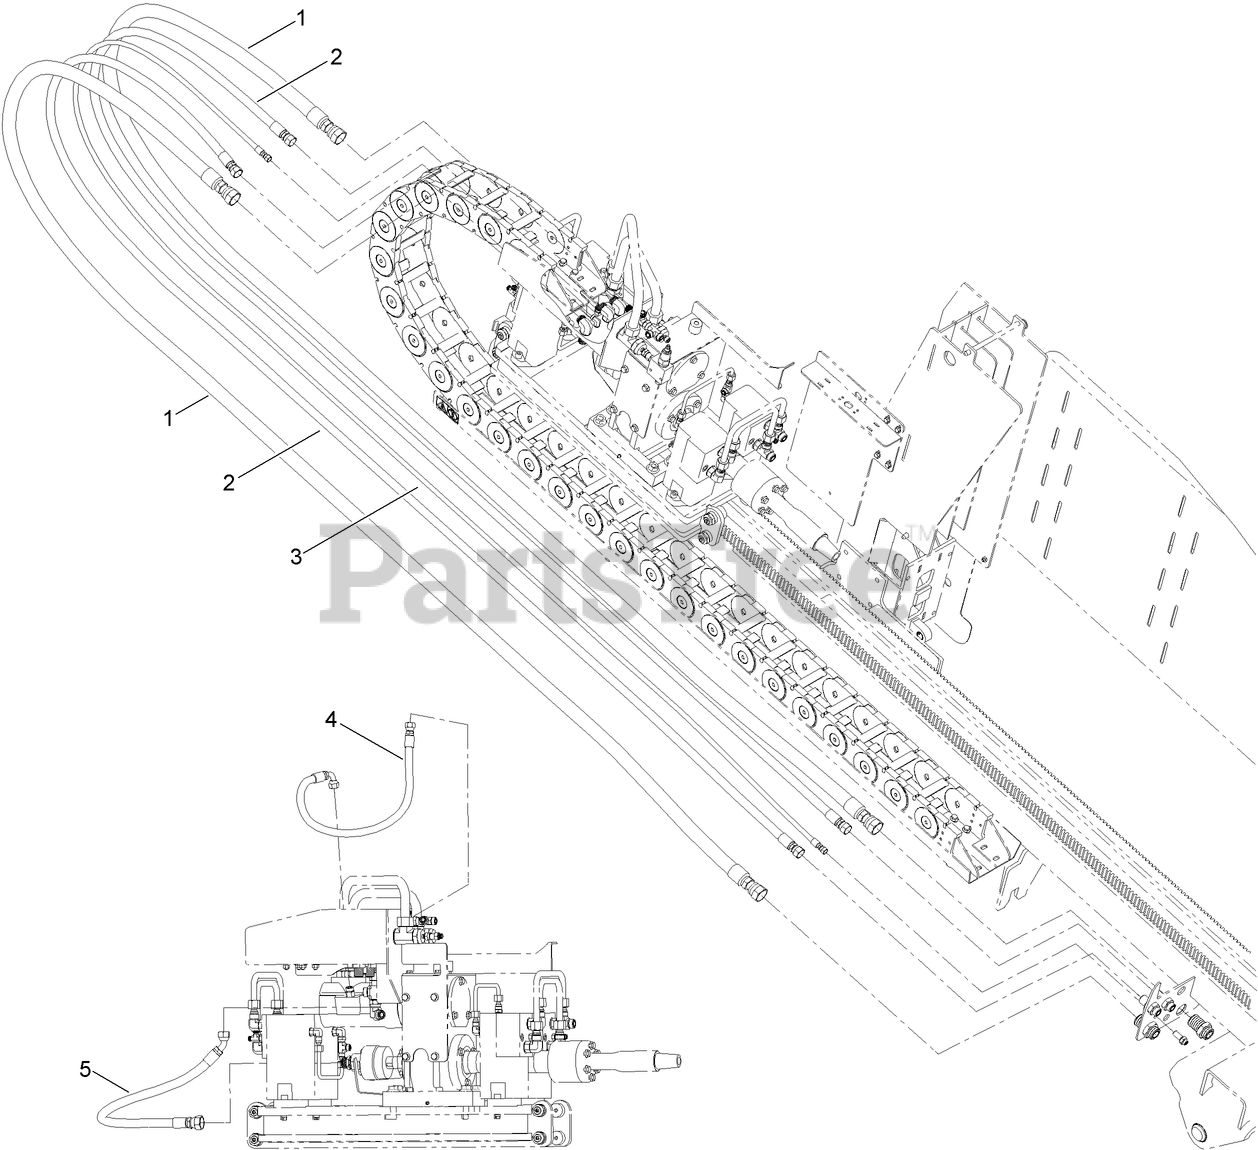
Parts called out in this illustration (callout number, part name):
1	HOSE ASM
2	HOSE ASM
3	HOSE ASM
4	HOSE ASM
5	HOSE ASM
